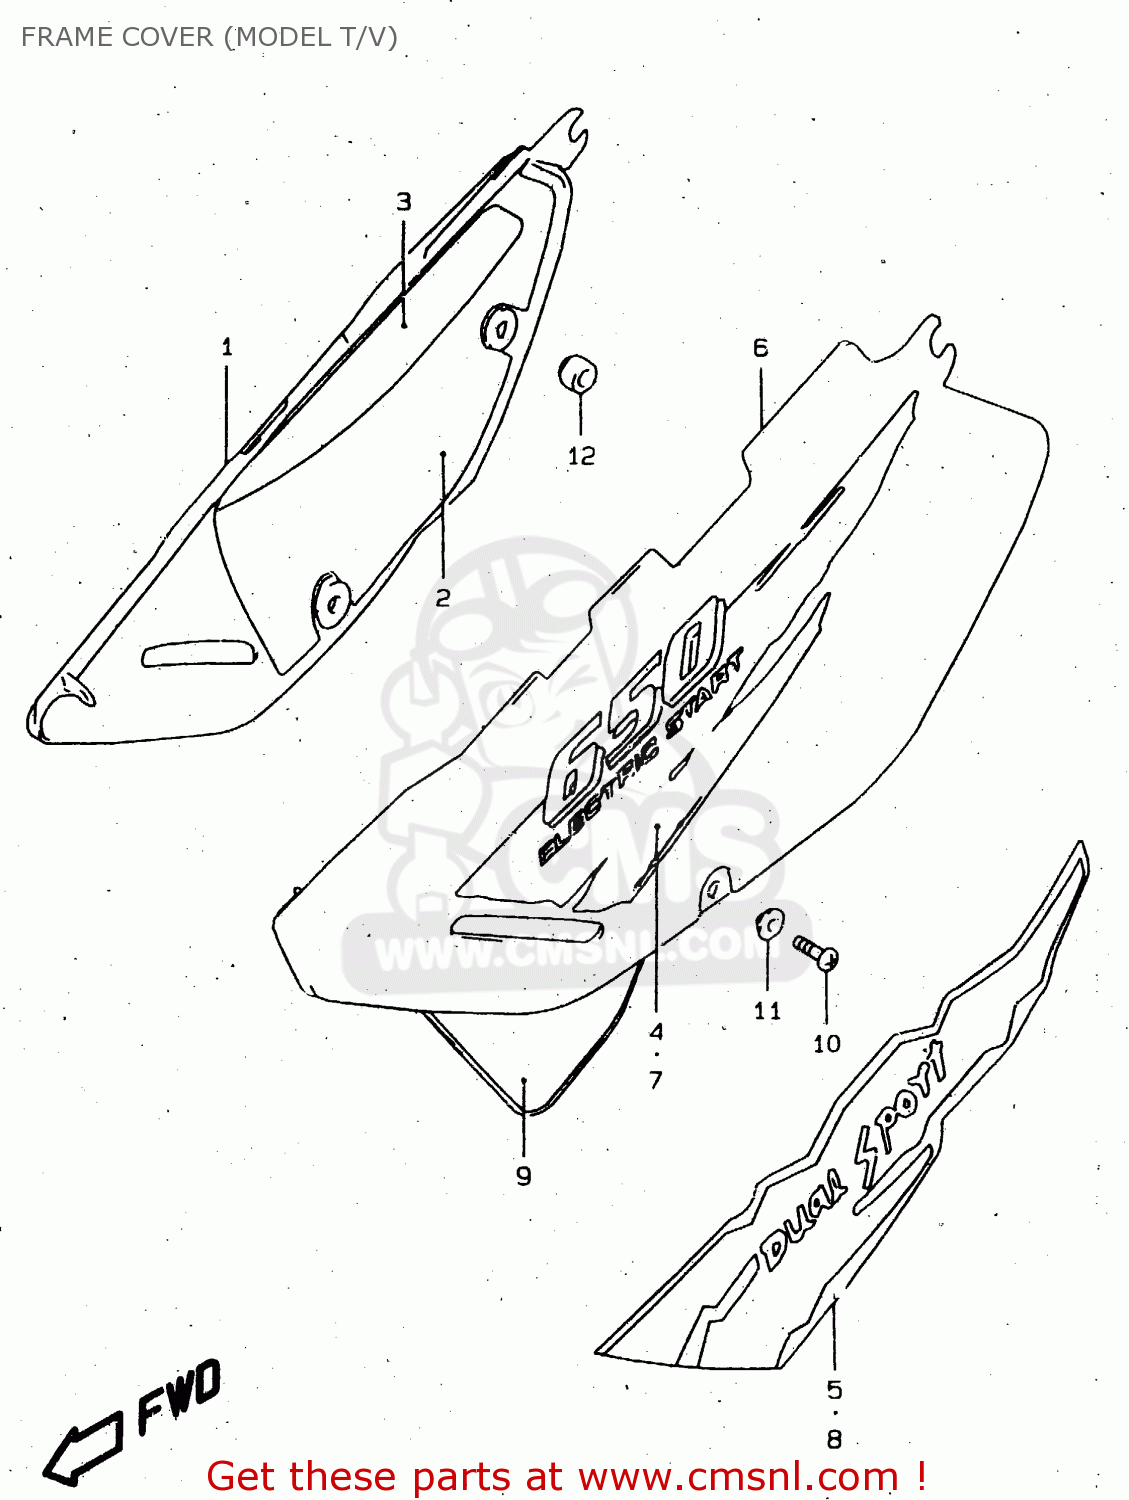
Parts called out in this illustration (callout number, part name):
1	COVER,FRAME,RIGHT
2	SHIELD,FRAME COVER,R NO.1
3	SHIELD,FRAME COVER,R NO.2
4	TAPE,FRAME COV
5	TAPE,FRAME COVER,R
6	COVER,FRAME,LEFT
7	TAPE,FRAME COVER,L
8	TAPE,FRAME COVER,L
9	TAPE,LWR
10	SCREW
11	WASHER
12	CUSHION
